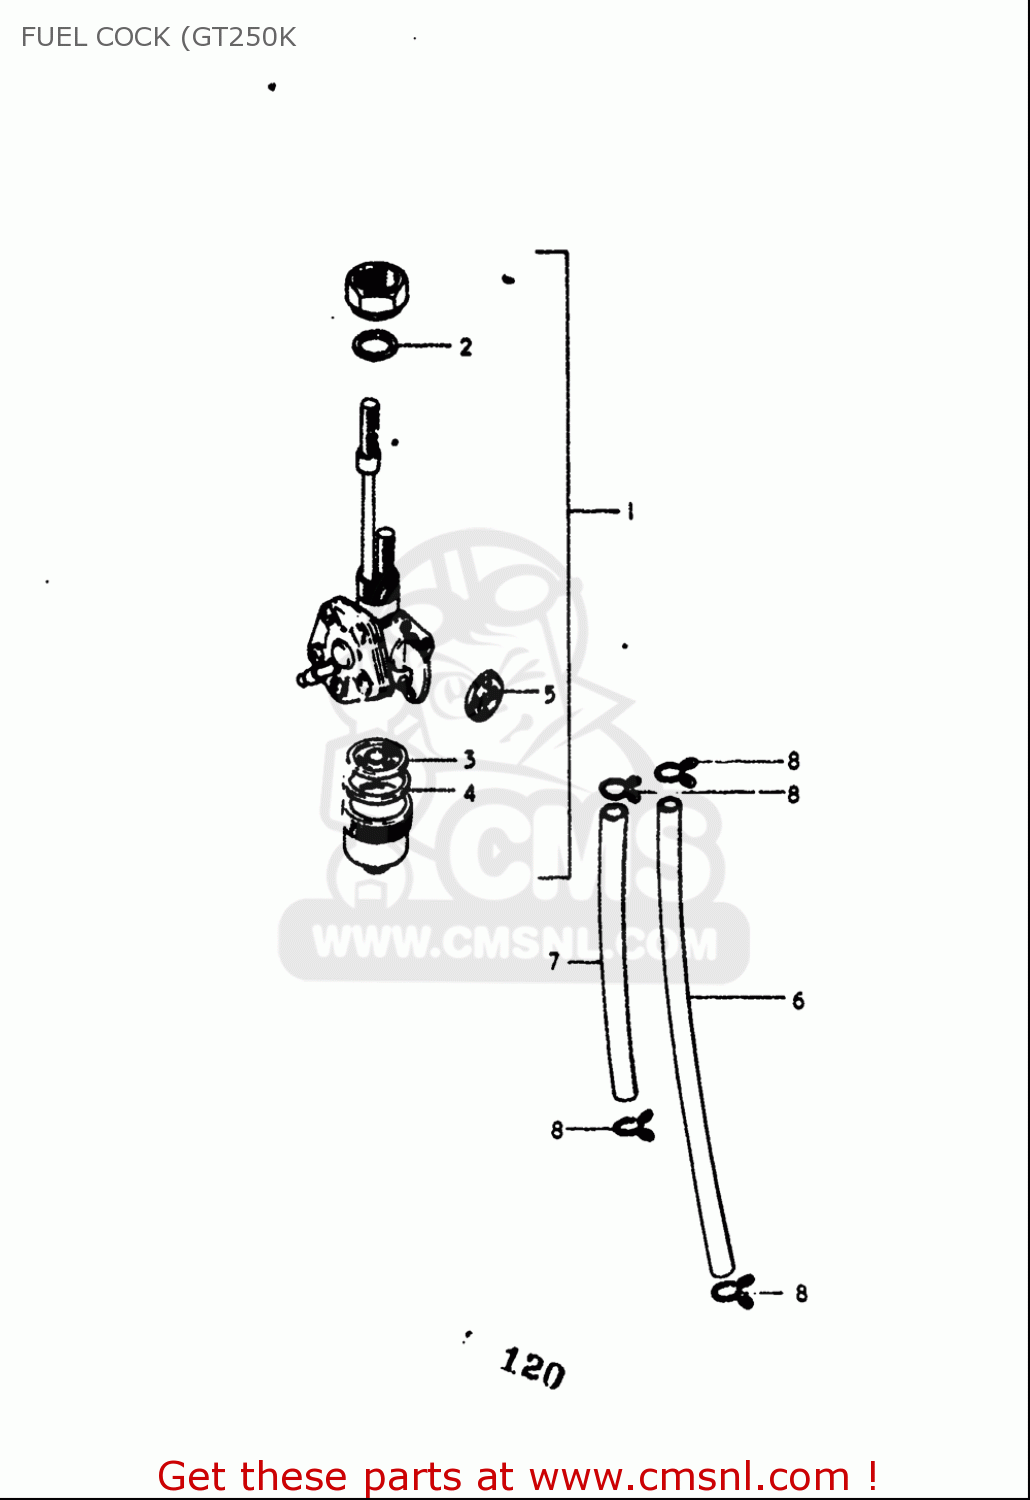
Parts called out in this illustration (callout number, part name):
1	COCK ASSY,FUEL
2	GASKET,FUEL COCK (NAS)
4	GASKET,CLEANER CUP (NAS)
5	GASKET,LEVER (NAS)
6	HOSE(5X9X600)
7	HOSE(5X9X600)
8	CLIP
